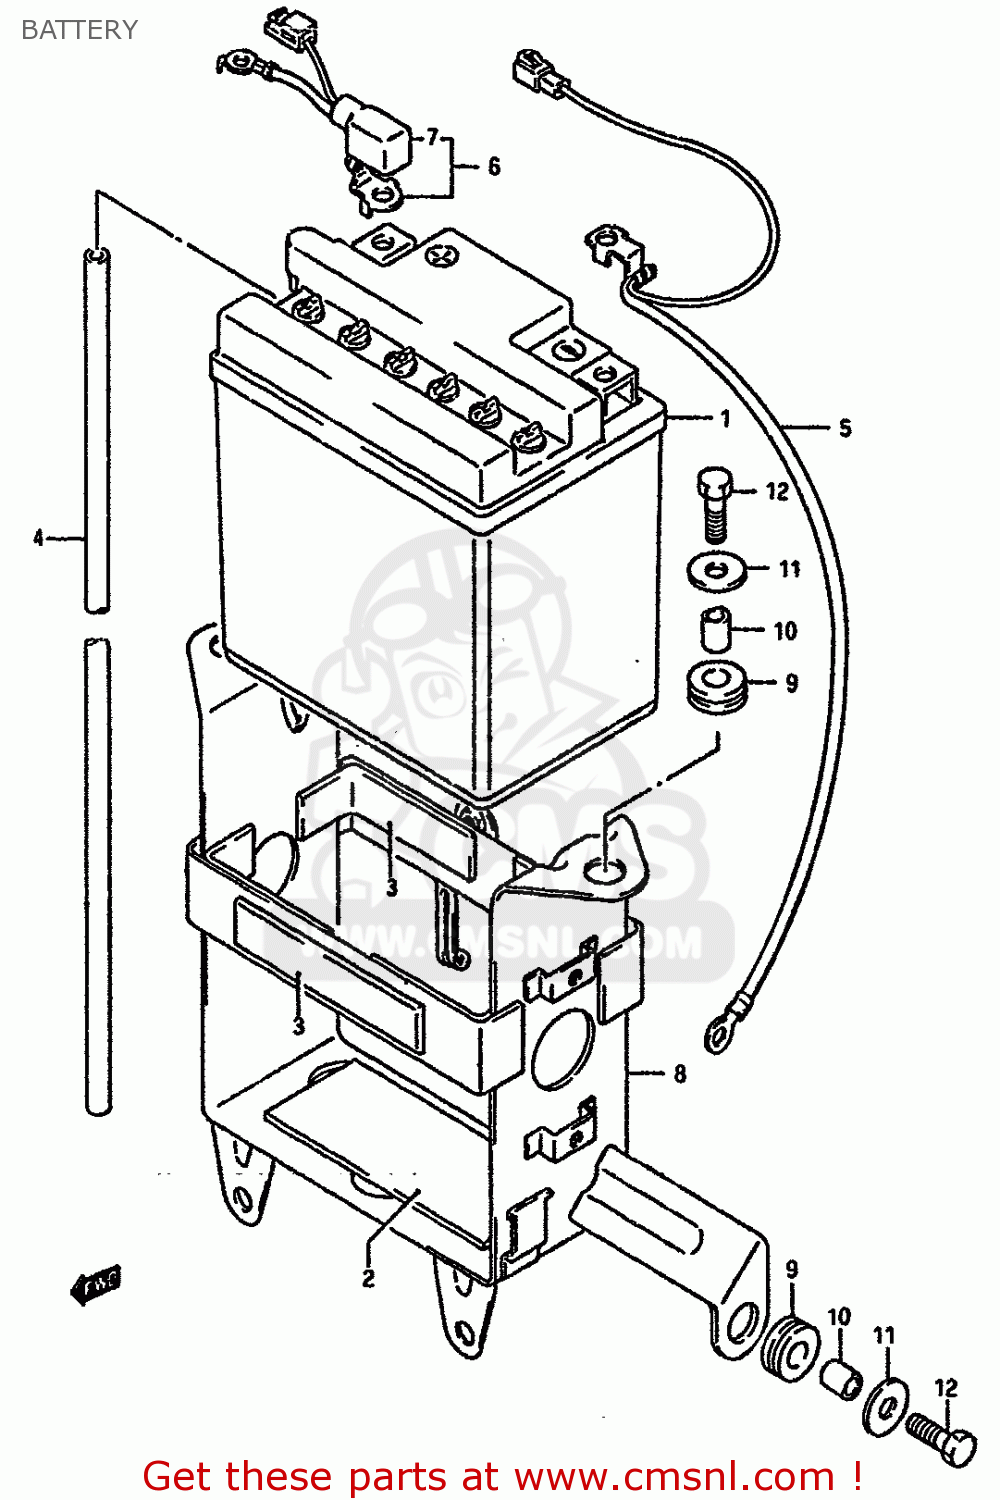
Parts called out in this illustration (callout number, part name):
1	BATTERY(YB14L-B2,12V14.7AH)
2	PROTECTOR(170X95X3.0)
3	PROTECTOR,20X9
4	HOSE,BATTERY EXHAUST
5	LEAD WIRE,BATTERY (-)
6	LEAD WIRE,BATTERY (+)
7	CAP,BATTERY PLUS
8	HOLDER,BATTERY
9	CUSHION
10	SPACER(6.1X9X7.5)
11	WASHER (6.5X20X1.2)
12	BOLT
